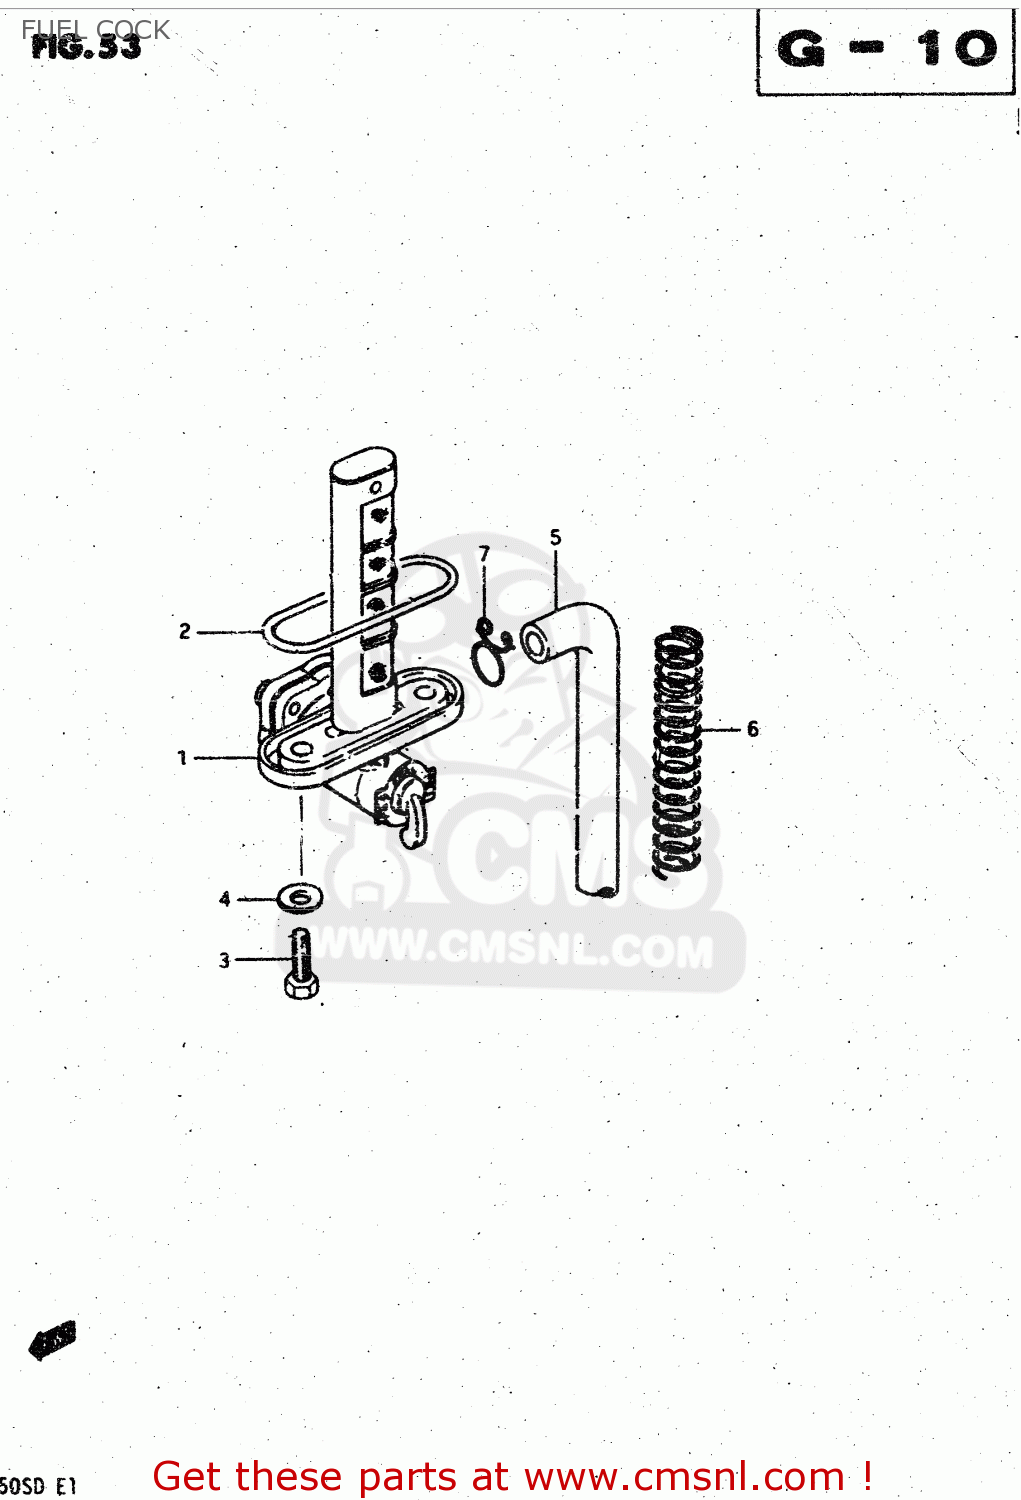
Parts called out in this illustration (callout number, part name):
1	COCK ASSEMBLY,FUEL
2	O RING
3	BOLT(6X20)
4	GASKET
5	HOSE
6	SPRING
7	CLIP
